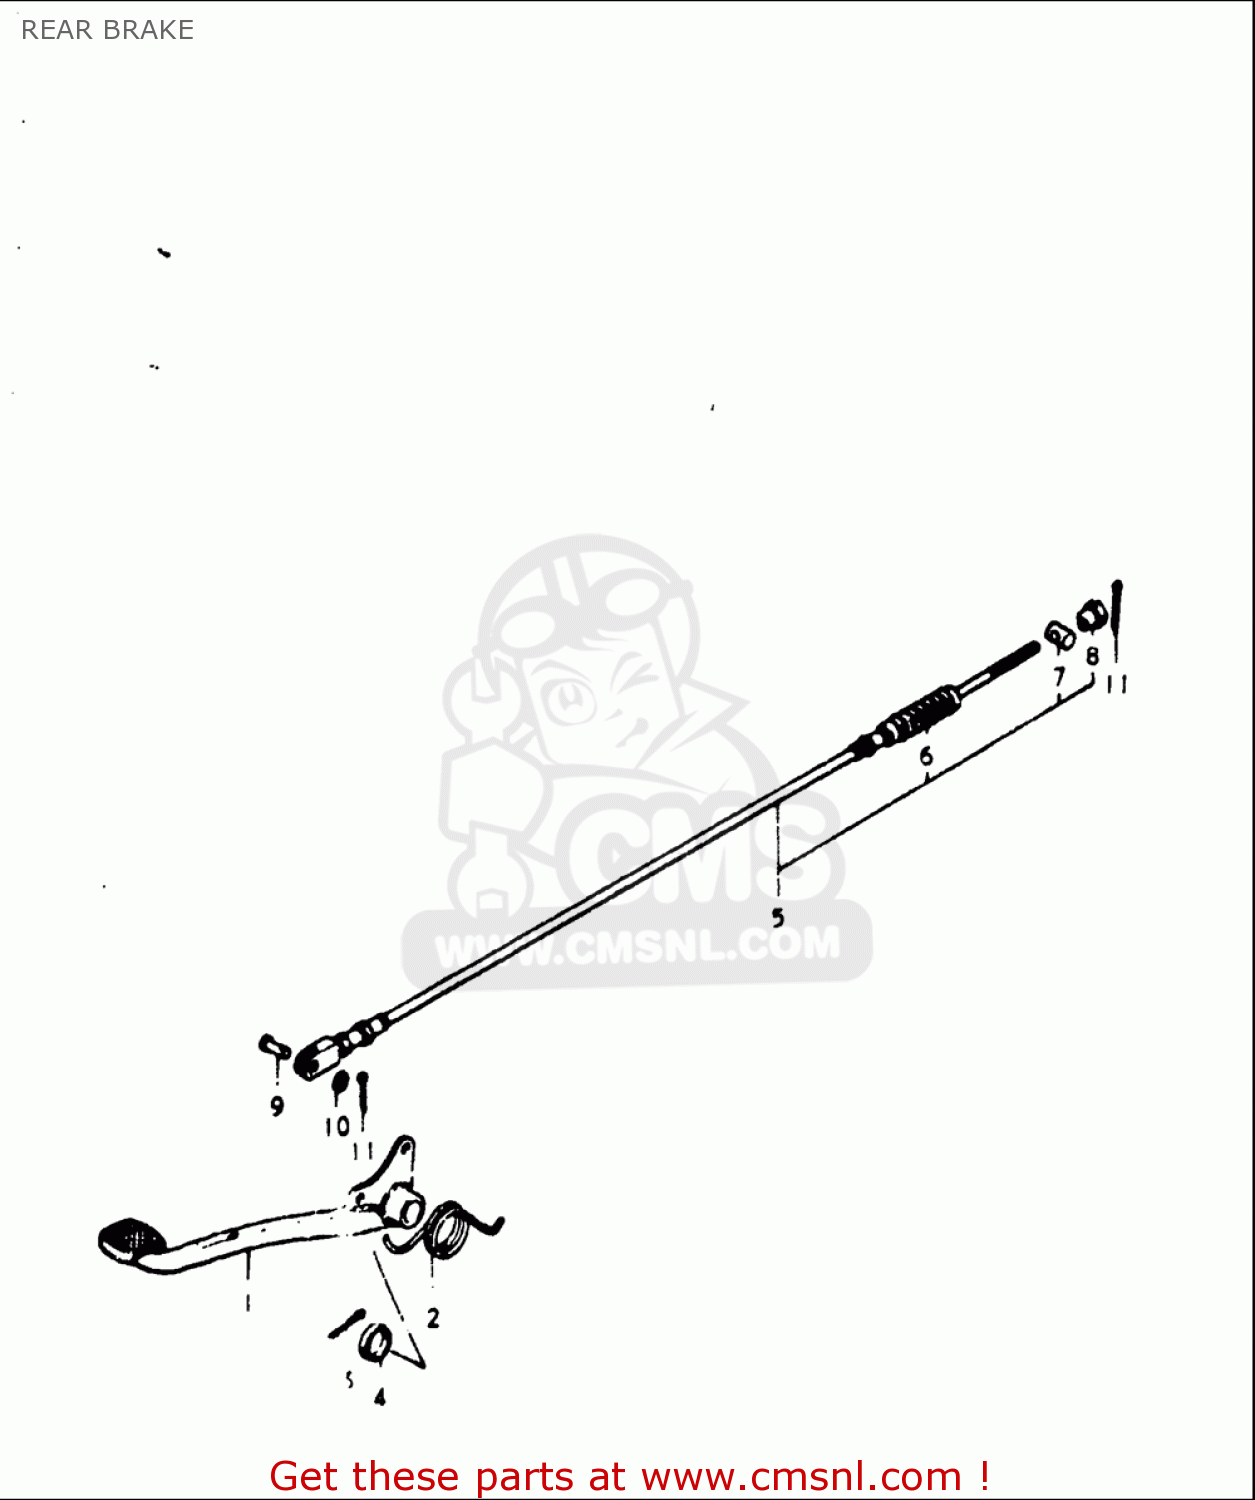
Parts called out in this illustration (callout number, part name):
2	SPRING
3	PIN, COTTER
6	SEAL,DUST
7	PIN(13X18)
8	NUT
9	PIN(L:17.5)
10	WASHER
11	PIN
